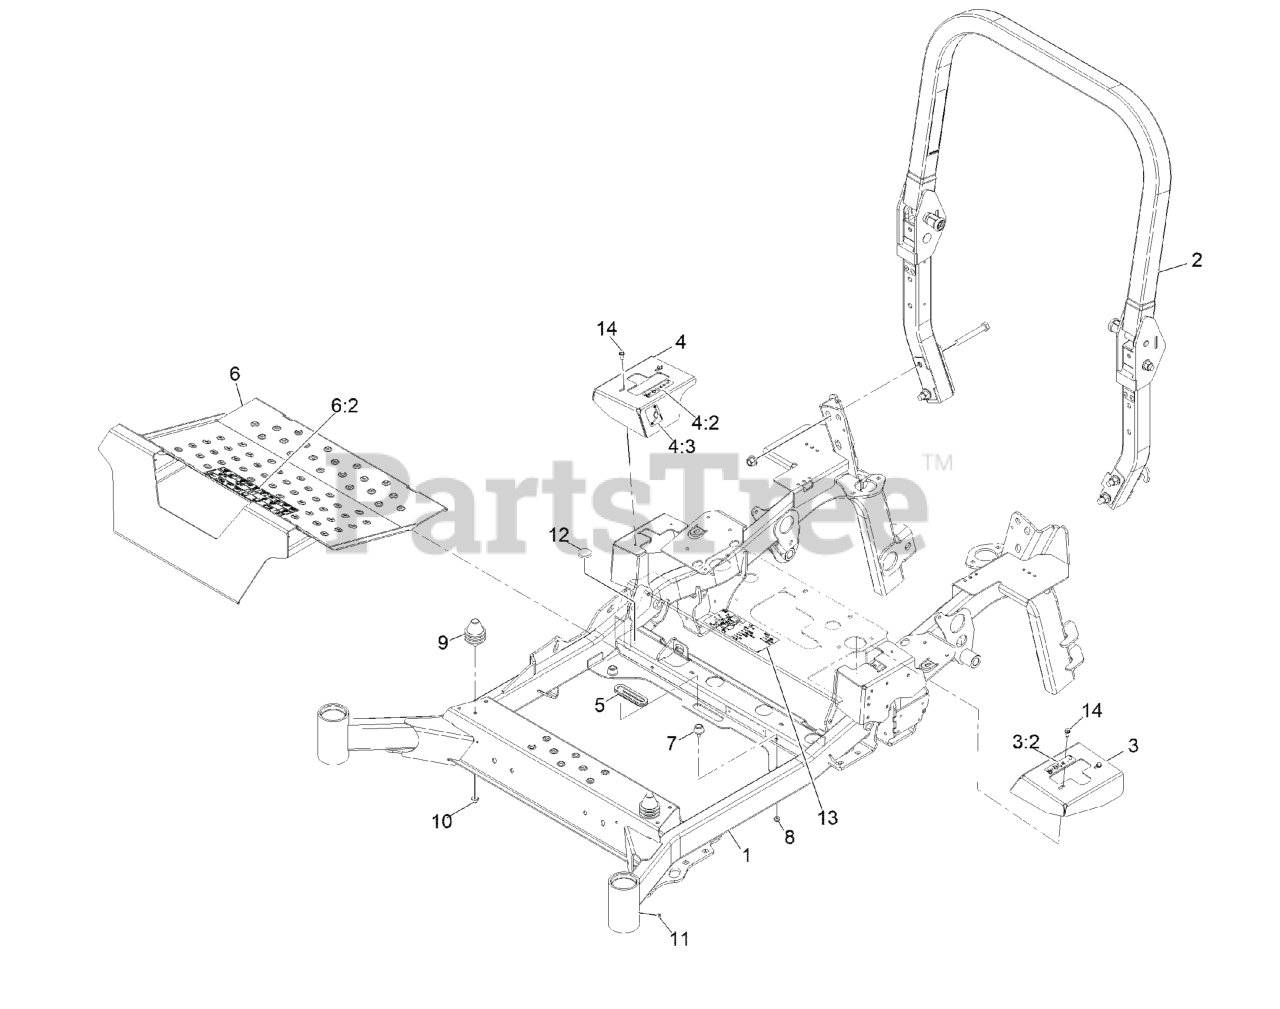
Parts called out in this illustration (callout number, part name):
2	ROPS ASM
3	COVER-MOTION CONTROL, LH
3:2	DECAL-CONTROL, MOTION
4	COVER-MOTION CONTROL, RH
4:2	DECAL-CONTROL, MOTION
4:3	DECAL-PARK BRAKE, CE
5	GROMMET-RUBBER
6	PAN-FLOOR
6:2	DECAL-DANGER
7	BUMPER-RUBBER
9	ISOLATOR
10	NUT-HF, NI
12	BUMPER-PUSH-IN, RUBBER
13	DECAL-SERVICE AID
14	SCREW-HWH
